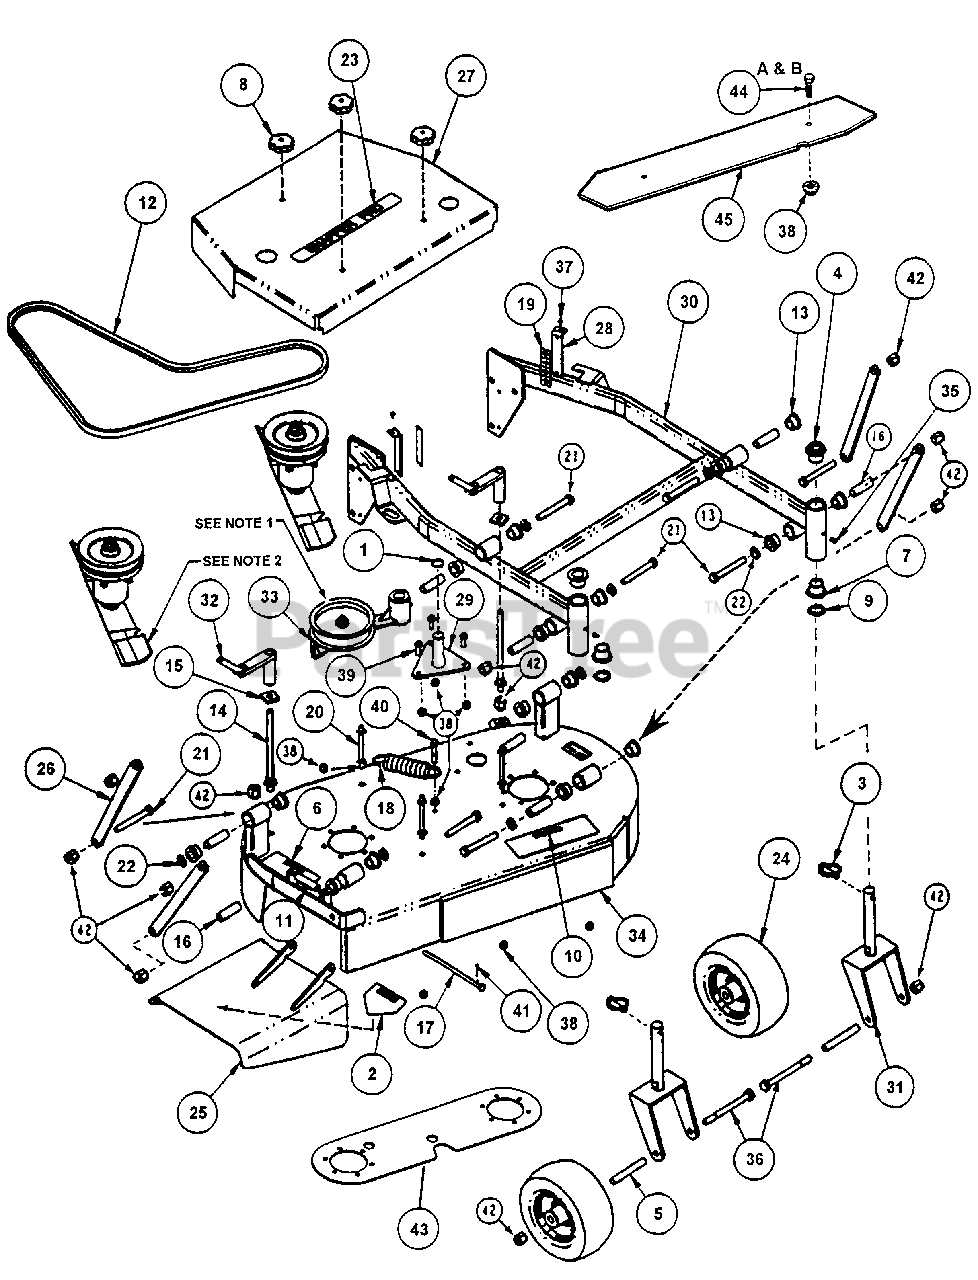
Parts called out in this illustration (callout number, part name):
1	SNAP-RING, 1" External
2	DECAL, Warning (CPSC Cut Finger)
3	PIN, 7/16" Head Lynch
4	SPACER, 1" x 1 3/8 x .30" (PM)
5	SLEEVE/SPACER, Axle
6	DECAL, Warning
7	BUSHING, Caster
8	KNOB, Hood
9	BUSHING, 1"
10	DECAL, Caution- Operator Instruction
11	SPRING, Chute
12	V-BELT, Deck Drive 36"
13	BUSHING, Suspension
14	STUD, Lift
15	WASHER, Lift
16	SLEEVE, Suspension
17	HINGE PIN, Chute
18	SPRING, Idler
19	DECAL, Height-of-Cut
20	STANDOFF, 3-1/2"
21	BOLT, 1/2-13 x 3-3/4" Grade 5
22	WASHER, 1/2" Flat
23	DECAL, Snapper Pro
24	ASSEMBLY, Wheel/Tire
25	DEFLECTOR, Chute Red
26	ARM, Suspension
27	COVER, 36"
28	BRACKET, Height-of-Cut
29	PIVOT, Idler (Weldment)
30	FRAME, 36" Adjustable (Weldment)
31	CASTER Weldment
32	ASSEMBLY, Crank
33	ASSEMBLY, Idler Arm 36"
34	ASSEMBLY, Deck Red Adjustable Height
35	FITTING, Lube 1/4-28 Straight
36	BOLT, 1/2-13 X 5-1/2" GD5 YZ
37	SCREW, 1/4-20 x 3/8" Hex Washer Self-Tap
38	NUT, 3/8-16 HEX SERRATED FLANGE
39	BOLT, 3/8-16 X 1" GD5 CZ
40	BOLT, 3/8-16 X 2, GD5, CZ
41	PIN, 3/32 x 1" Cotter
42	NUT, 1/2-13 Nyloc
43	PLATE, Stiffner (7 Ga.)
44A	BOLT, 3/8-16 X 2, GD5, CZ
44B	BOLT, 3/8-16 X 1-1/4" GD5 CZ
45	COUNTERWEIGHT
